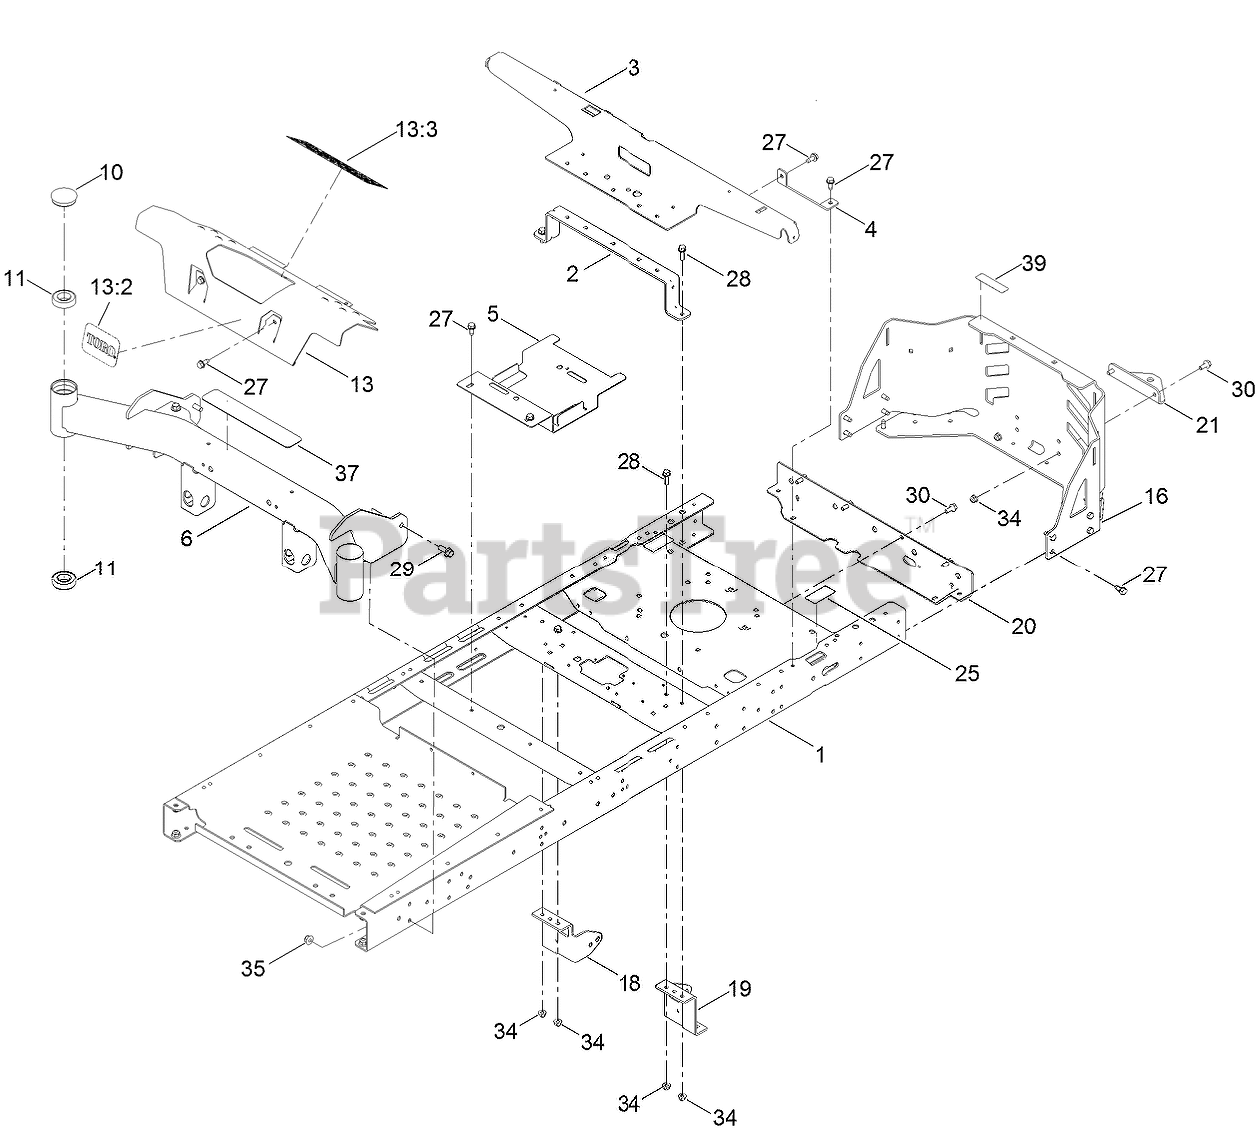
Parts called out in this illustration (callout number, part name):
1	RIVETED FRAME ASM (WIDE LEVER)
2	BRACE-SEAT, REAR (WIDE)
3	SUPPORT-POD
4	SUPPORT-TANK, REAR
5	BRACKET-BATTERY
6	FRONT AXLE ASM
10	CAP-GREASE
11	BEARING-BALL
13	FOOTREST
13:3	DECAL-DANGER
16	GUARD-ENGINE
18	MOUNT-HYDRO, FRONT (RIGHT)
19	MOUNT-HYDRO, FRONT (LEFT)
20	CROSSMEMBER-REAR, WIDE
21	BRACKET-HITCH
25	DECAL-BYPASS
27	SCREW-HWHTF
28	SCREW-HHF
29	SCREW-HHF
30	SCREW-HHF
34	NUT-HF, NI
35	NUT-HF, NI
37	TREAD-STEP
39	DECAL-BUCKET
